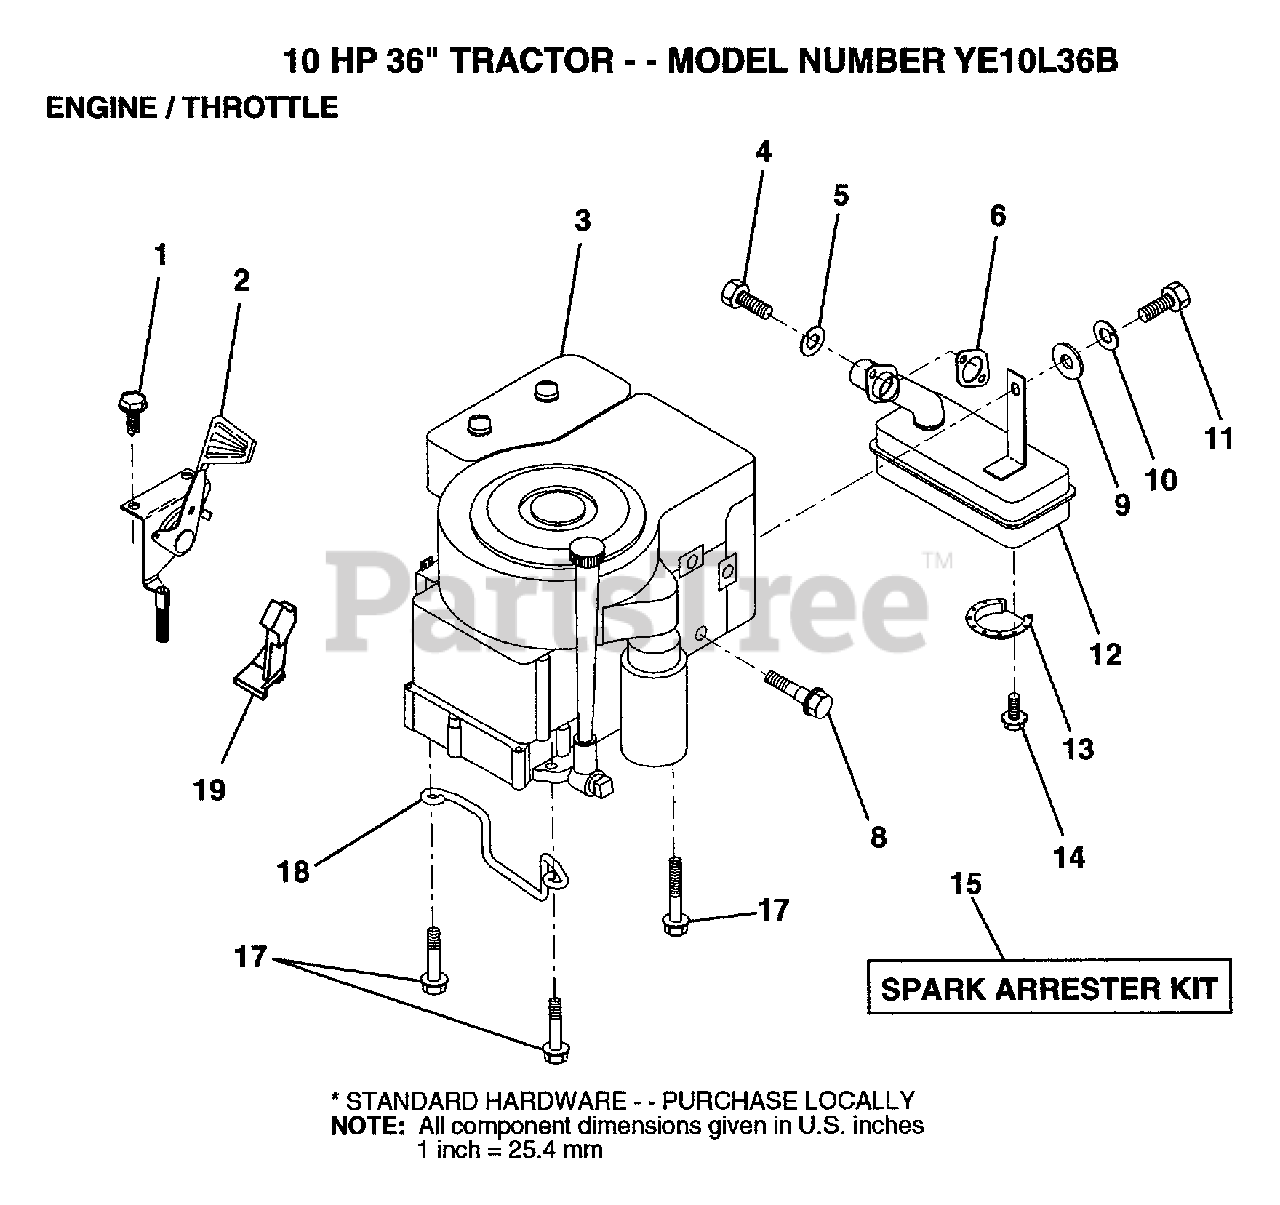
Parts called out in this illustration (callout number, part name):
1	SCREW
2	"CONTROL,THROTTLE"
3	ENGINE BRIGGS AND STRATTON
4	SCREW
5	LOCKWASHER
8	BOLT T
10	LOCKWASHER
13	DEFLECTOR.222573
17	SCREW LT
18	"KEEPER,DR BELT GR"
19	"STOP,DASH THROTT"
